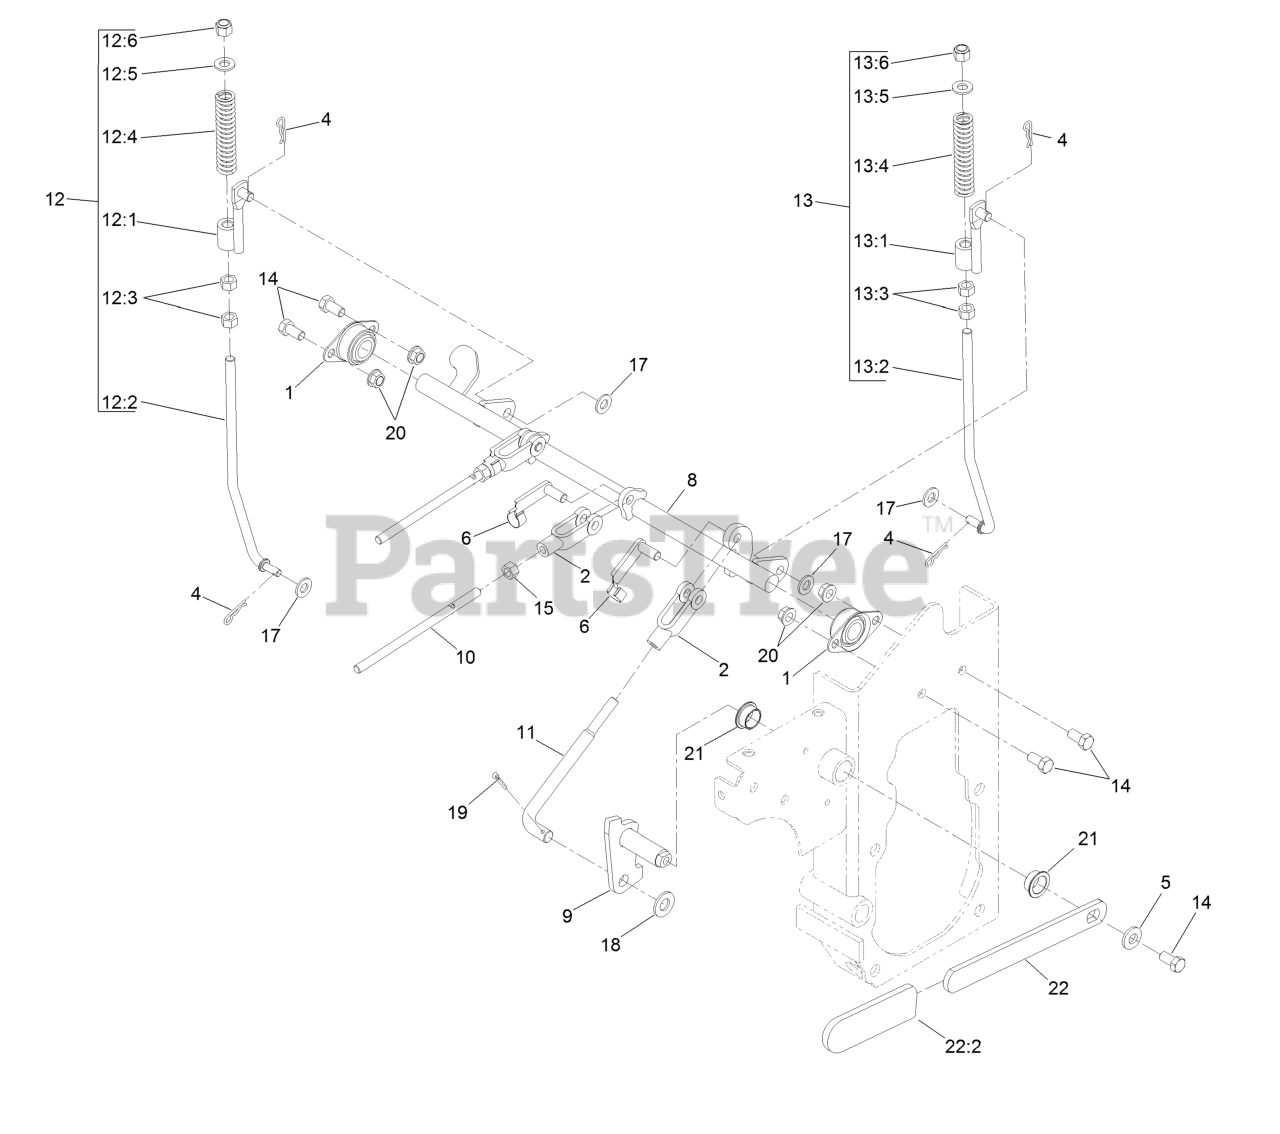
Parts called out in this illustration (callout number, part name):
1	Bearing-Flange, Side
2	Yoke-Linkage, Brake
4	Pin-Cotter
5	Washer-Belleville
6	Pin-Spring, Clevis
8	Shaft-Brake
9	Pivot-Brake
10	Rod-Linkage, Brake
11	Rod-Linkage, Brake
12	RH Brake Linkage ASM
12:1	Brake Linkage ASM
12:2	Link-Brake, RH
12:3	Nut-Hex
12:4	Spring-Compression
12:5	Washer-Flat
12:6	Nut-Lock
13	LH Brake Linkage ASM
13:1	Brake Linkage ASM
13:2	Link-Brake, LH
13:3	Nut-Hex
13:4	Spring-Compression
13:5	Washer-Flat
13:6	Nut-Lock
14	Screw-HH
15	Nut-Hex
17	Washer-Flat
18	Washer-Flat
19	Pin-Cotter
20	Nut-HHF, Whiz
21	Bushing-Bronze
22	Park Brake Handle ASM
22:2	Grip-Lever
